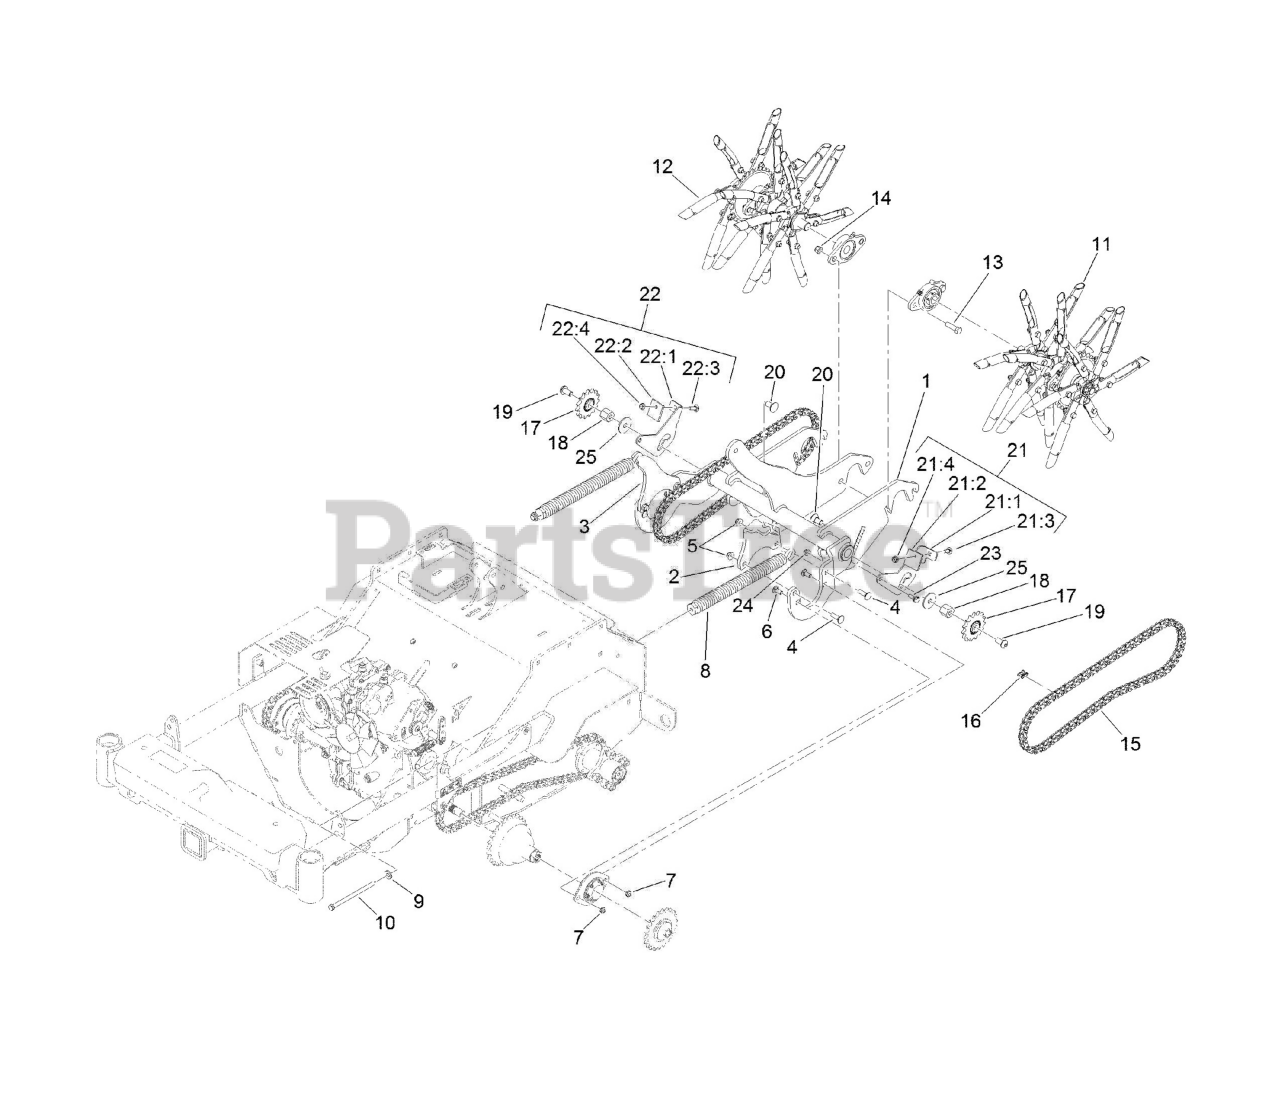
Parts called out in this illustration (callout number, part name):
1	LIFT-TINE
2	ARM-SPRING, LH
3	ARM-SPRING, RH
4	BOLT-CARR
5	NUT-HF, NI
6	BOLT-CARR
8	SPRING-EXTENSION
9	WASHER-BELLEVILLE
10	BOLT-TAP, HH
11	LH TINE WHEEL ASM
12	RH TINE WHEEL ASM
14	NUT-LOCK
15	CHAIN-ROLLER
16	LINK-CONNECTING
17	SPROCKET-IDLER, 15T
19	SCREW- PAN SOCKET HEAD
20	SCREW-CARR
21	LH DEBRIS DEFLECTOR ASM
21:1	BRACKET-DEFLECTOR, DEBRIS
21:2	DEFLECTOR-DEBRIS
21:3	BOLT-CARR
21:4	NUT-HF, NI
22	RH DEBRIS DEFLECTOR ASM
22:1	BRACKET-DEFLECTOR, DEBRIS
22:2	DEFLECTOR-DEBRIS
22:3	BOLT-CARR
22:4	NUT-HF, NI
23	SCREW-SHOULDER
24	NUT-HF, NI
25	WASHER-FLAT
